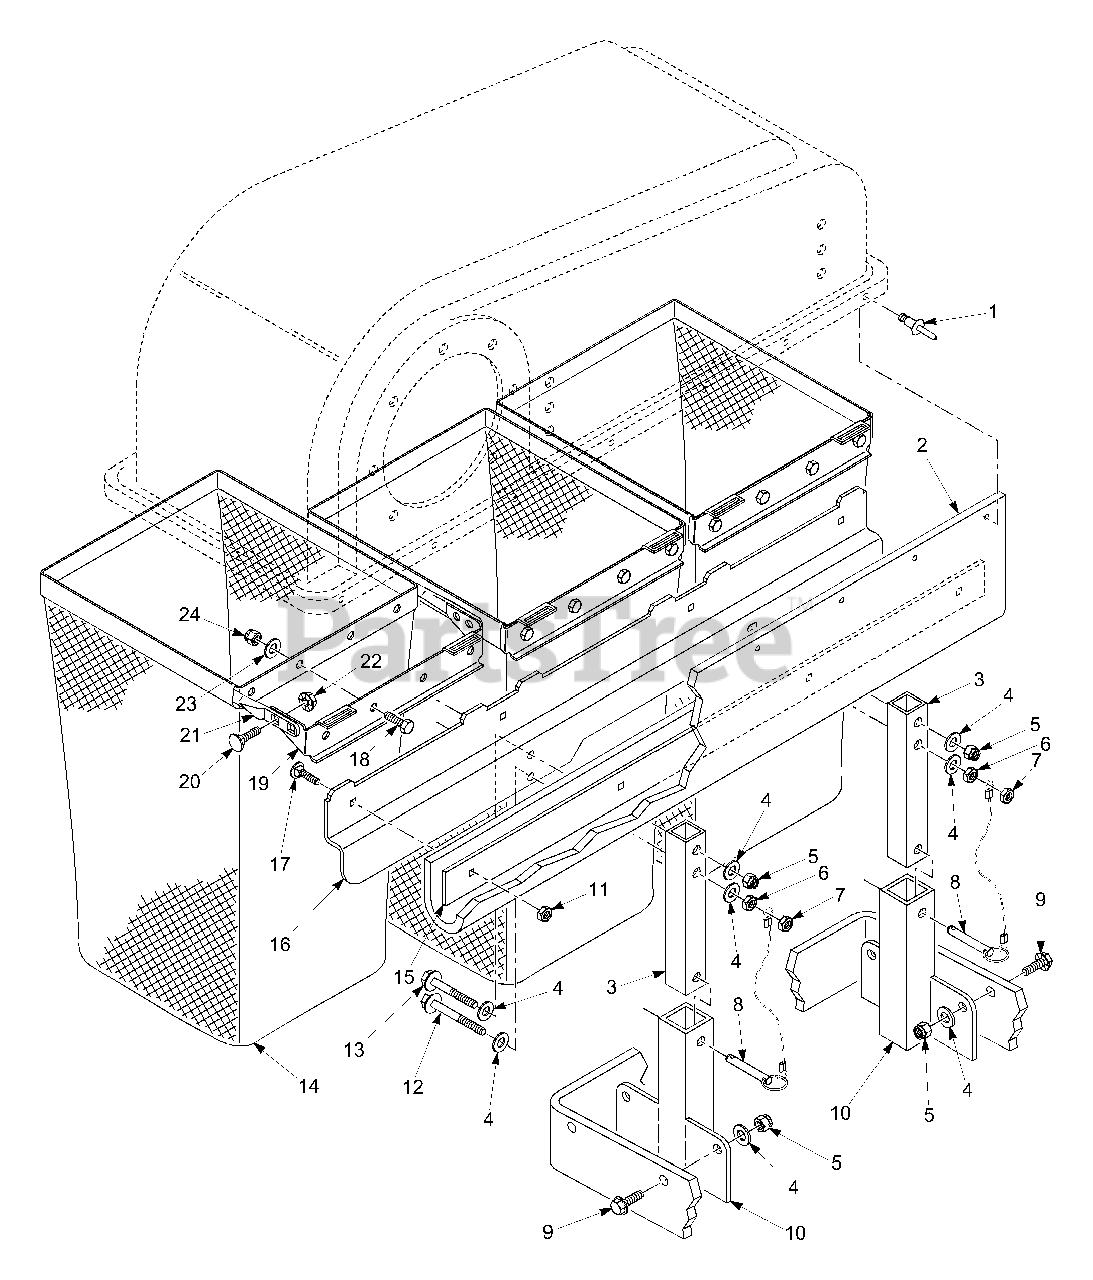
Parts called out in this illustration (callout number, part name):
1	Pop Rivet, 3/16 x .652
2	Seal, Hood
3	Tube, Upright
4	Flatwasher, 3/8-.391 x .938 x .105
5	Nut, Elastic Stop 3/8-16
6	Nut, 3/8-16
7	Hex Lock Nut, 3/8-16
8	Pin, Ring 1/2 x 2-1/4"
9	Bolt, Hex Head 3/8-16 x 1"
10	Mounting Plate Weldment
11	Lock Nut, 1/4-20 Center
12	Bolt, Hex Head 3/8-16 x 2-3/4"
13	Bolt, Hex Head 3/8-16 x 2-1/2"
14	Bag Assembly, GC-STC
15	Retainer, Seal
16	Support, Bag Frame
17	Bolt, Carr. 1/4-20 x 3/4"
18	Bolt, Hex Head 5/16-18 x 3/4"
19	Mount, Bag Frame Tube
20	Bolt, Carr. 5/16-18 x 3/4"
21	Tube, Bag Support
22	Nut, Serr. Flange 5/16-18
23	Flatwasher, 5/16-.375 x .875 x .083
24	Nut, Elastic Stop 5/16-18
